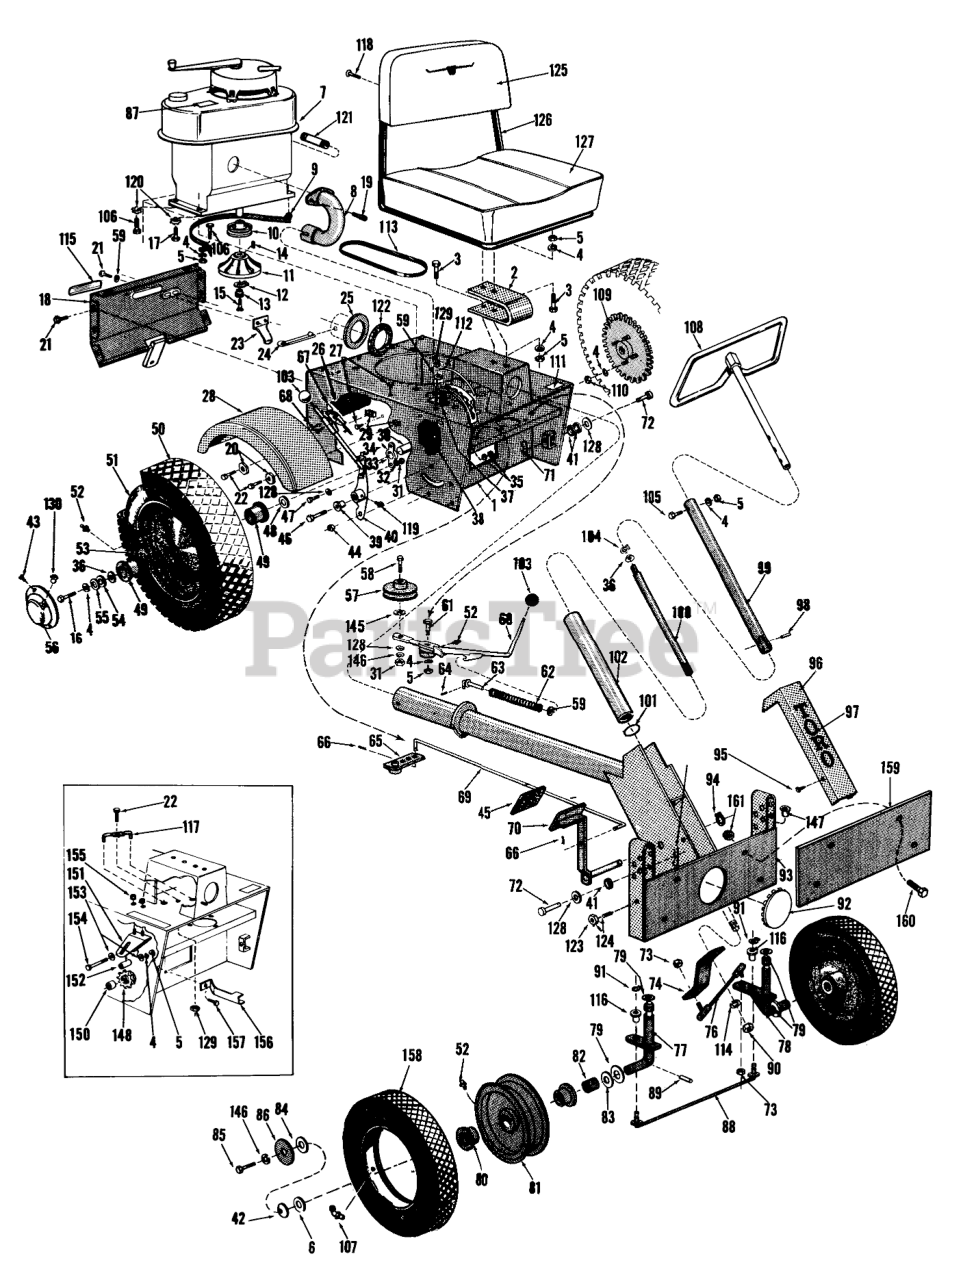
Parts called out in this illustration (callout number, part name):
1	Rear Housing
2	Seat Spring
3	SCREW-HH
4	WASHER-LOCK
5	NUT-HEX
6	Spacer
7	Engine
8	Exhaust Tube Assembly
9	Belt Retainer
10	Pulley
11	Friction Plate
12	7/8X046 IN SNAP RING
13	Spacer
16	SCREW-HH
17	SCREW-HH
18	Rear Cover
19	SCREW-HSH
20	Washer
21	1/4-20X1/2 THDG SEMS
22	SCREW-HH
23	Bracket, Neutral
24	PIN-COTTER
25	Tube Retainer
26	Muffler
27	SCREW-HH
28	Fender
29	TINNERMAN NUT
30	Axle Shaft
31	NUT-HEX
32	WASHER-LOCK
33	Shaft Retainer
34	PIN-ROLL
35	NUT-JAM
36	3/4 SPRING WASHER
37	Shift Quadrant
38	SCREW-HH
39	Bushing
40	Shift Lever Assembly
41	Rubber Washer
42	Spring Washer
43	SCREW-HWHTF
44	NUT-LOCK NI
46	SCREW-HH
47	SCREW-HH
48	Washer
49	Bushing
50	TIRE - 2 PLY - STUD TREAD
51	4.00-8 TUBE
52	FITTING-GREASE
53	Wheel Assy. with Bushing
54	WASHER-THRUST
55	WASHER
56	Hub Cap
57	Pulley
58	SCREW-HH
59	WASHER-FLAT
60	Lever
61	Shoulder Bolt
62	Compression Spring
63	Pivot Rod
64	PIN-COTTER
65	Engaging Arm Assy.
66	PIN-COTTER
67	Throttle Control
68	SCREW-HWHTF
69	Brake Rod
70	Foot Pedal
71	PIN-COTTER, HAIR
72	Pin, Clevis
73	NUT-LOCK NI
74	Steering Plate
76	Ball Joint Assembly
77	Spindle and Bushing, R.H.
78	Spindle and Bushing, L.H.
79	Washer, Thrust
80	Bushing
81	Wheel & Hub Assy. (Incl. Ref. No. 80)
82	Bushing
83	WASHER-FLAT
84	Washer
85	SCREW-HH
86	Hub Cap
87	Decal
88	Tie Rod
89	PIN-ROLL, SLOTTED
90	NUT-HH
91	RING-GRIP
92	Plug Button
93	Front End
94	Grip Ring
95	SCREW-HWH
96	Cover
97	Decal
98	Roll Pin
99	Steering Tube
100	Spindle
101	"O" Ring
102	Pivot Lock Tube
104	Locknut
105	SCREW-HH
106	SCREW-HH
107	VALVE -STEM
108	Steering Wheel
109	Sprocket
110	NUT-HEX
111	Decal
112	Decal
114	WASHER-LOCK
115	Decal
116	Bushing
117	Belt Retainer
118	Screw
119	FITTING-LUBE, 45 DEG
120	Lockwasher
121	U-Bolt
122	Washer
123	NUT-JAM
124	SCREW-SET, HS
125	Seat Back
126	Seat Frame
128	WASHER-FLAT
129	NUT-KEPS
130	CAP-PLASTIC
145	Spacer
146	WASHER-LOCK
148	SPROCKET & BRG ASM
150	Bearing
151	Idler Bracket
152	Spindle
153	WASHER-PLAIN
154	SCREW-HH
155	NUT-KEPS
156	Belt Guide
157	1/4-20X5/8 THDG SEMS
159	Plate, Spindle Support
160	SCREW-HH
161	NUT-HEX
